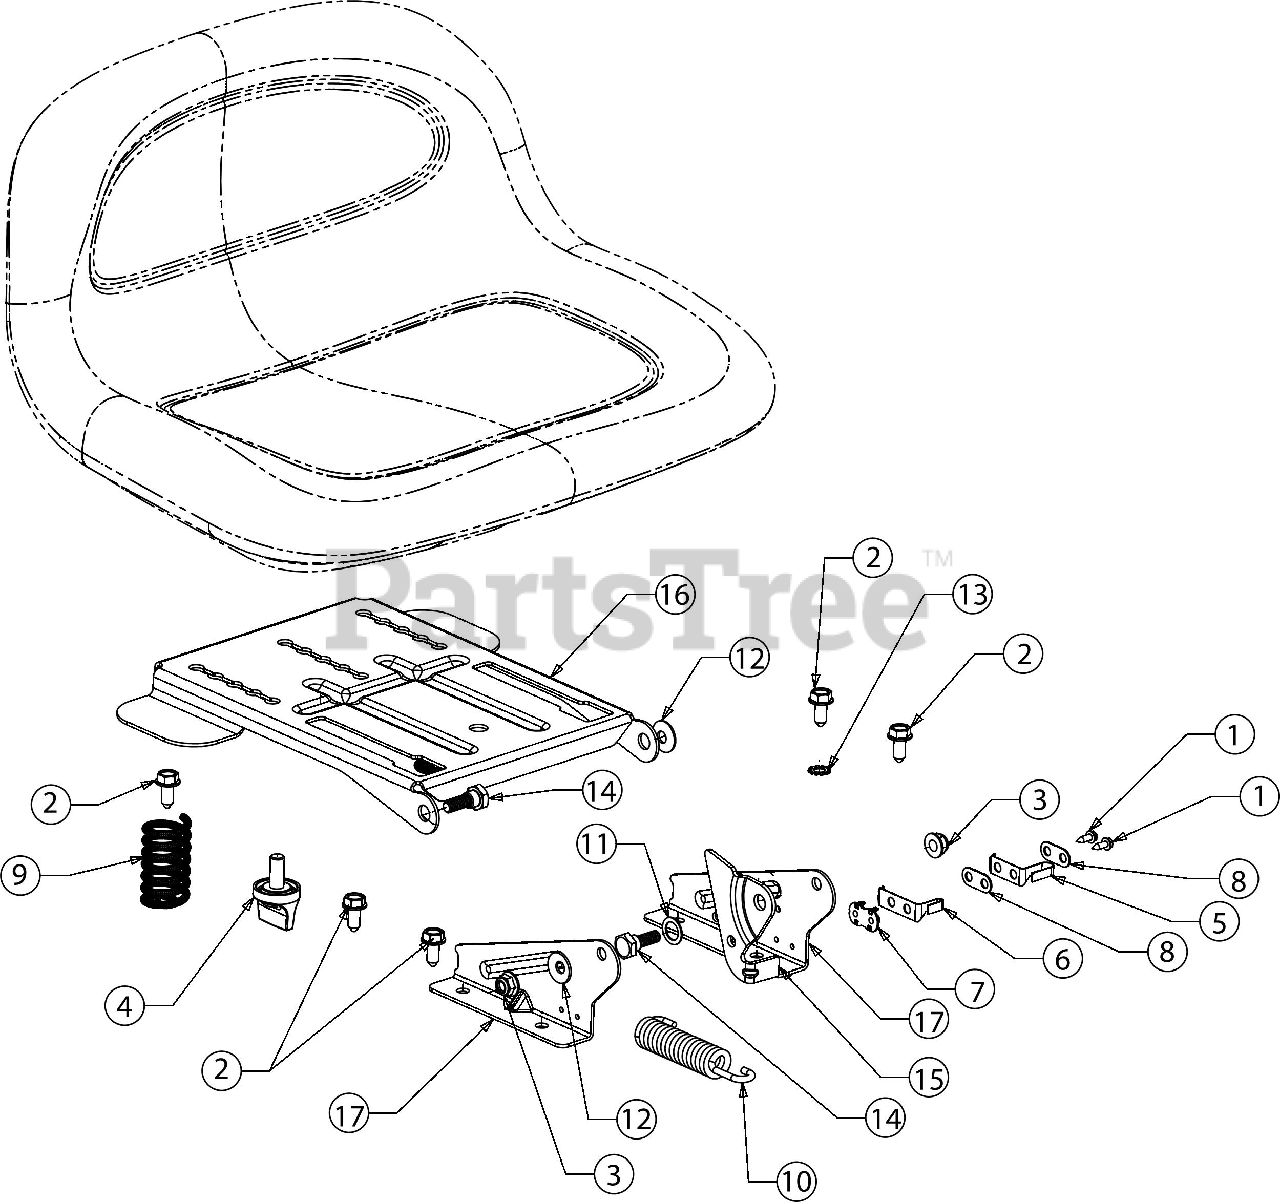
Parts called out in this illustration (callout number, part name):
1	HEX SCREW WASHER HD #8-18 X 0.500
2	SCREW 5/16-18 X .750
3	FLANGE LOCK NUT 5/16-18
5	SPRING SWITCH
6	SEAT SPRING SWITCH
7	INSULATOR BOSS PLATE
8	INSULATOR PLATE
9	COMPRESSION SPRING
10	EXTENSION SPRING .84DIA X 4.6 LG"
11	WASHER .510 X .750 X .033
12	BELL WASHER .337 X.867 X .057
14	SHOULDER SCREW .437
15	SEAT LIFT BRACKET
16	SEAT PIVOT BRACKET
